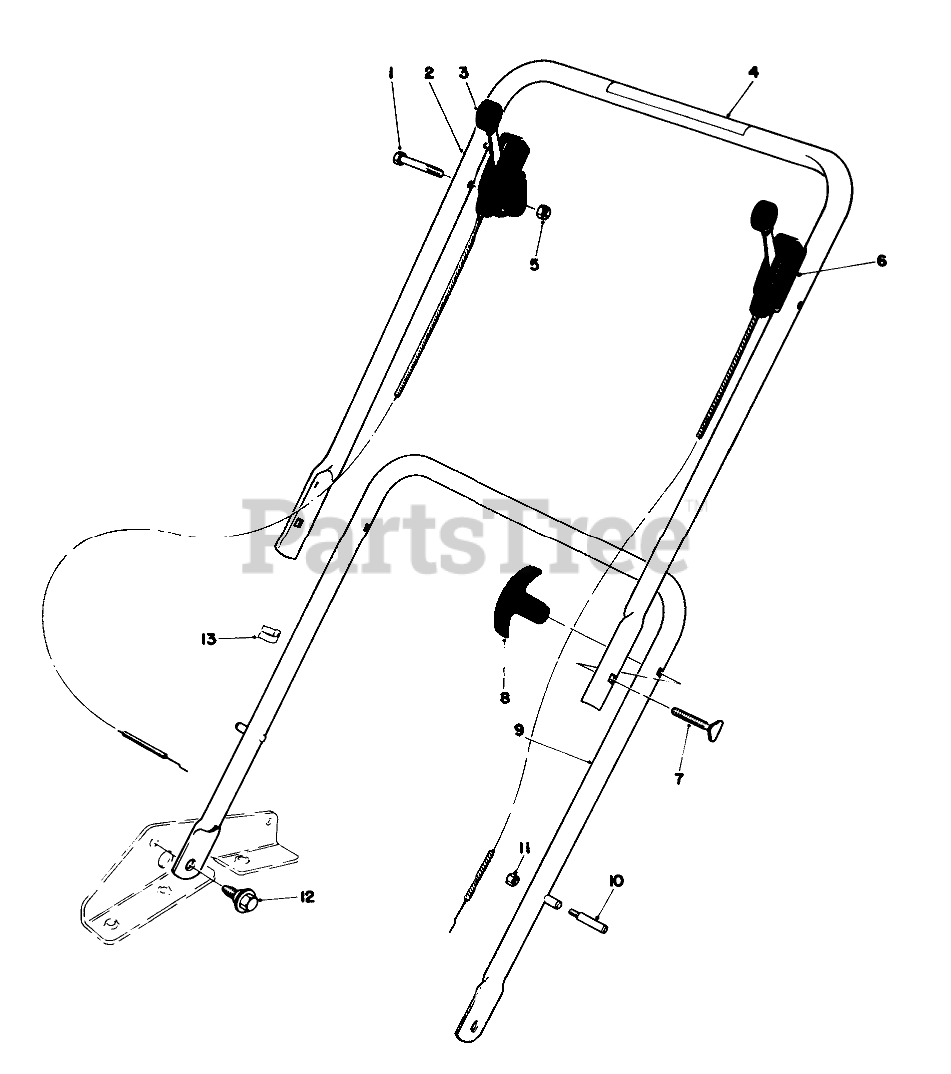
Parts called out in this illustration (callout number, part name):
1	SCREW-HH
2	Upper Handle
3	Throttle Control
4	Decal
5	NUT-LOCK
6	Traction Control
7	HANDLE SCREW
9	LOWER HANDLE ASM SP
10	HANDLE PIN
11	Nut
12	SCREW-SHOULDER
